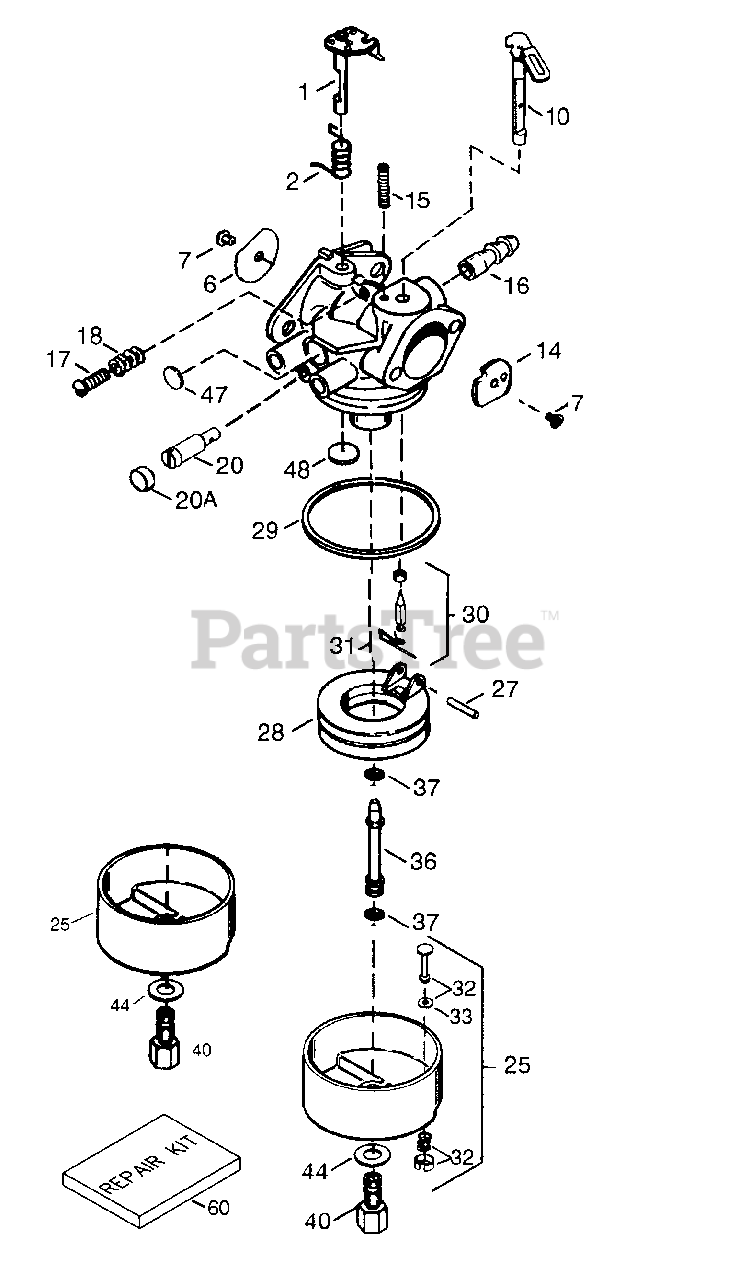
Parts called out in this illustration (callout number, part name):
1	Throttle Shaft & Lever Assembly
2	Throttle Return Spring
4	* Dust Seal Washer
5	* Dust Seal (Throttle)
6	Throttle Shutter
7	* Shutter Screw
10	Choke Shaft & Lever Assembly
11	Choke Return Spring
12	* Dust Seal Washer
13	* Dust Seal (Choke)
14	Choke Shutter
15	Choke Positioning Spring
16	Fuel Fitting
17	Throttle Crack Screw/Idle Speed Screw
18	Tension Spring
20	Idle Restrictor Screw
20A	Idle Restrictor Screw Cap
25	Float Bowl
27	* Float Shaft
28	Float
29	* Float Bowl "O" Ring
30	* Inlet Needle, Seat & Clip (Incl. 31)
31	Spring Clip
36	Main Nozzle Tube
37	* "O" Ring, Main Nozzle Tube
40	High Speed Bowl Nut
44	Bowl Nut Washer
47	* Welch Plug, Idle Mixture Well
48	* Welch Plug, Atmospheric Vent
60	Repair Kit Incl. items marked PK inn otes
